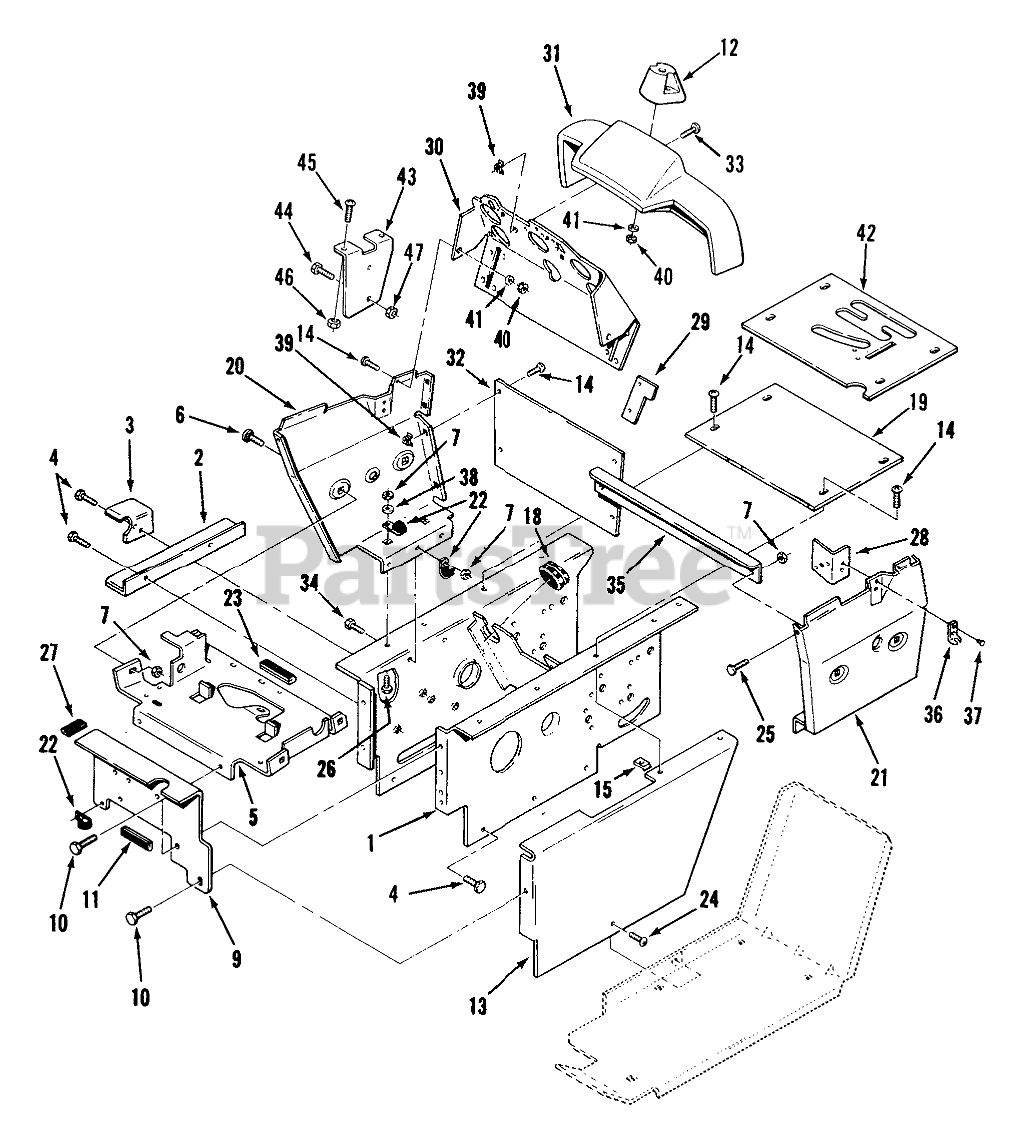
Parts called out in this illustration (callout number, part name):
1	Hoodstand
2	ANGLE-BELT GUARD B
3	Belt Bracket
4	SCREW
5	WLD-SUPPORTB
6	Bolt
7	Nut
9	PLATE-FRT HOODSTA B
10	SCREW
11	EDGE TRIM 2" 102896
12	COVER-STEERING SHAFT
13	COVER-L.H. R
14	SCREW-PPH
18	GROMMET
19	Control Bracket
20	Panel-RH
21	LS Panel
22	CLIP
23	EDGE TRIM 5" OF 102896
24	Screw
24	WASHER 5/16 SAE
25	H H C S
26	CARRIAGE BOLT -4
27	EDGE TRIM-BULK
28	BRACKET-SWITCH SU
29	STOP-CHOKE
30	Dash Panel
31	Kit-Console Cover (Contains #115620 5-Gauge Cover, #118410 Steering Cover, (4) 118780 Screw #6 Plastite, & (4) 920270 Washers)
32	Plate-Top Hoodstand
33	Screw
34	Bolt
35	STIFFENER-PANEL B
36	Latch Keeper (Included in 106825 Hood Latch)
37	RIVET
38	WASHER 5/16 SAE
39	Nut 1/4-20
40	Nut
43	Bracket-Holder
45	H H C S
46	Nut
47	Nut
